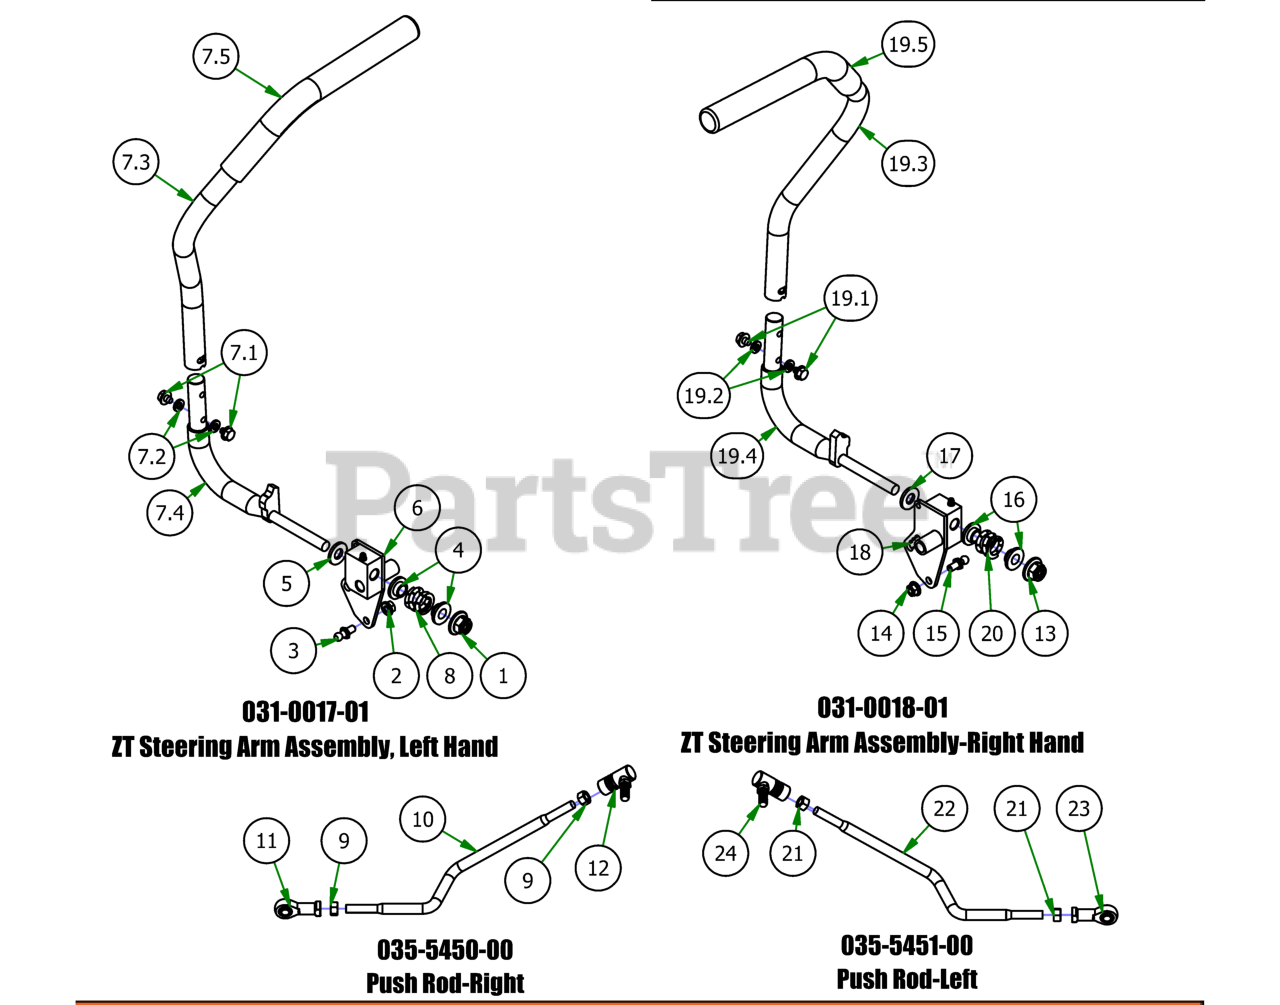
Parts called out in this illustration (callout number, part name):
1	1/2-13 Nylon Flange Nut
2	5/16" Flange Nut
3	10mm Damper Ball Stud-Steering
4	.515 ID Nylon Shoulder Washer
5	.505 Nylon Spacer
6	2017 Drive Lever Housing - Left
7	ZT Steering Arm-Left
7.1	5/16-18 1/2 HWH Bolt-Steering
7.2	5/16" Lock Washer
7.3	ZT Direction Steering Arm (Left)
7.4	Stering Arm Elbow (Left)
7.5	Rubber Grip
8	Drive Lever Spring
9	3/8" Fine Threaded Jam Nut
10	Push Rod - Right
11	Spherical Rod End - Outlaw
12	Quick Release Ball Joint
13	1/2-13 Nylon Flange Nut
14	5/16" Flange Nut
15	10mm Damper Ball Stud-Steering
16	.515 ID Nylon Shoulder Washer
17	.505 Nylon Spacer
18	2017 Drive Lever Housing - Right
19	ZT Steering Arm-Right
19.1	5/16-18 1/2 HWH Bolt-Steering
19.2	5/16" Lock Washer
19.3	ZT Direction Steering Arm (Right)
19.4	Stering Arm Elbow (Right)
19.5	Rubber Grip
20	Drive Lever Spring
21	3/8" Fine Threaded Jam Nut
22	Push Rod - Left
23	Spherical Rod End - Outlaw
24	Quick Release Ball Joint
